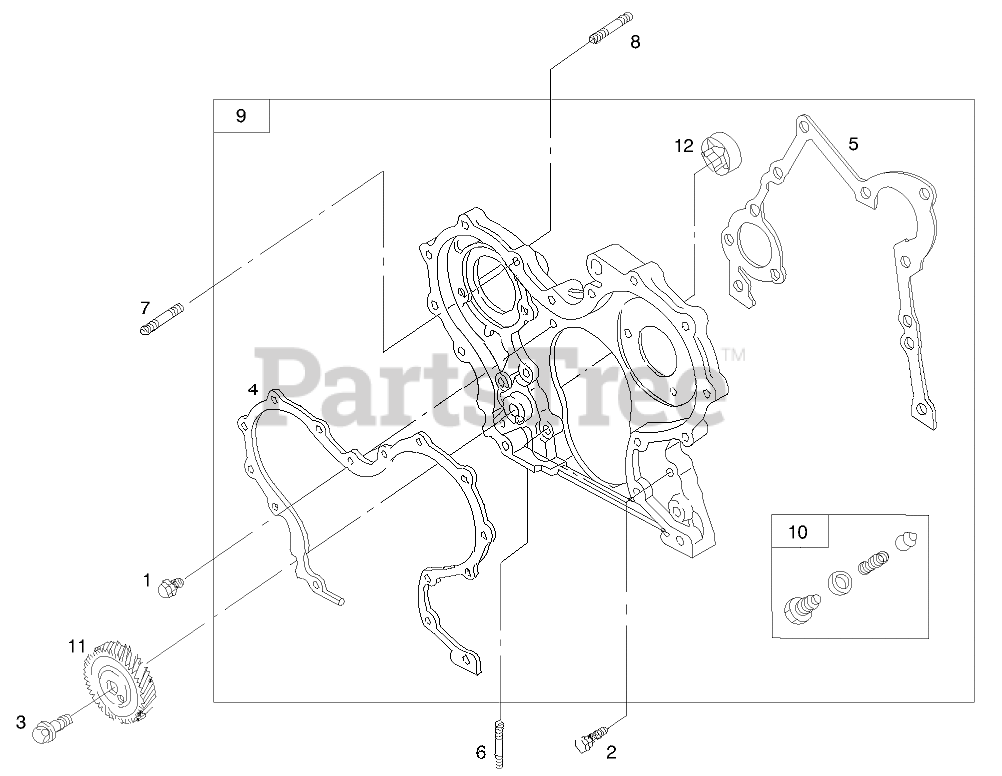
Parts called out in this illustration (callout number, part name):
1	SCREW-HEX
1	HEAD-CYLINDER
2	SCREW-HEX
3	SCREW-HEX
4	GASKET-COVER, GEAR
5	GASKET-COVER, GEAR
6	STUD-METRIC
7	STUD-METRIC
8	STUD-METRIC
8	SWITCH-TEMPERATURE, WATER
9	HOUSING-GEAR
9	GASKET-SET
10	VALVE-RELIEF, OIL
11	GEAR-DRIVE
12	Pump-Oil
14	KIT-VALVE OVERHAUL
15	SHAFT-GEAR
